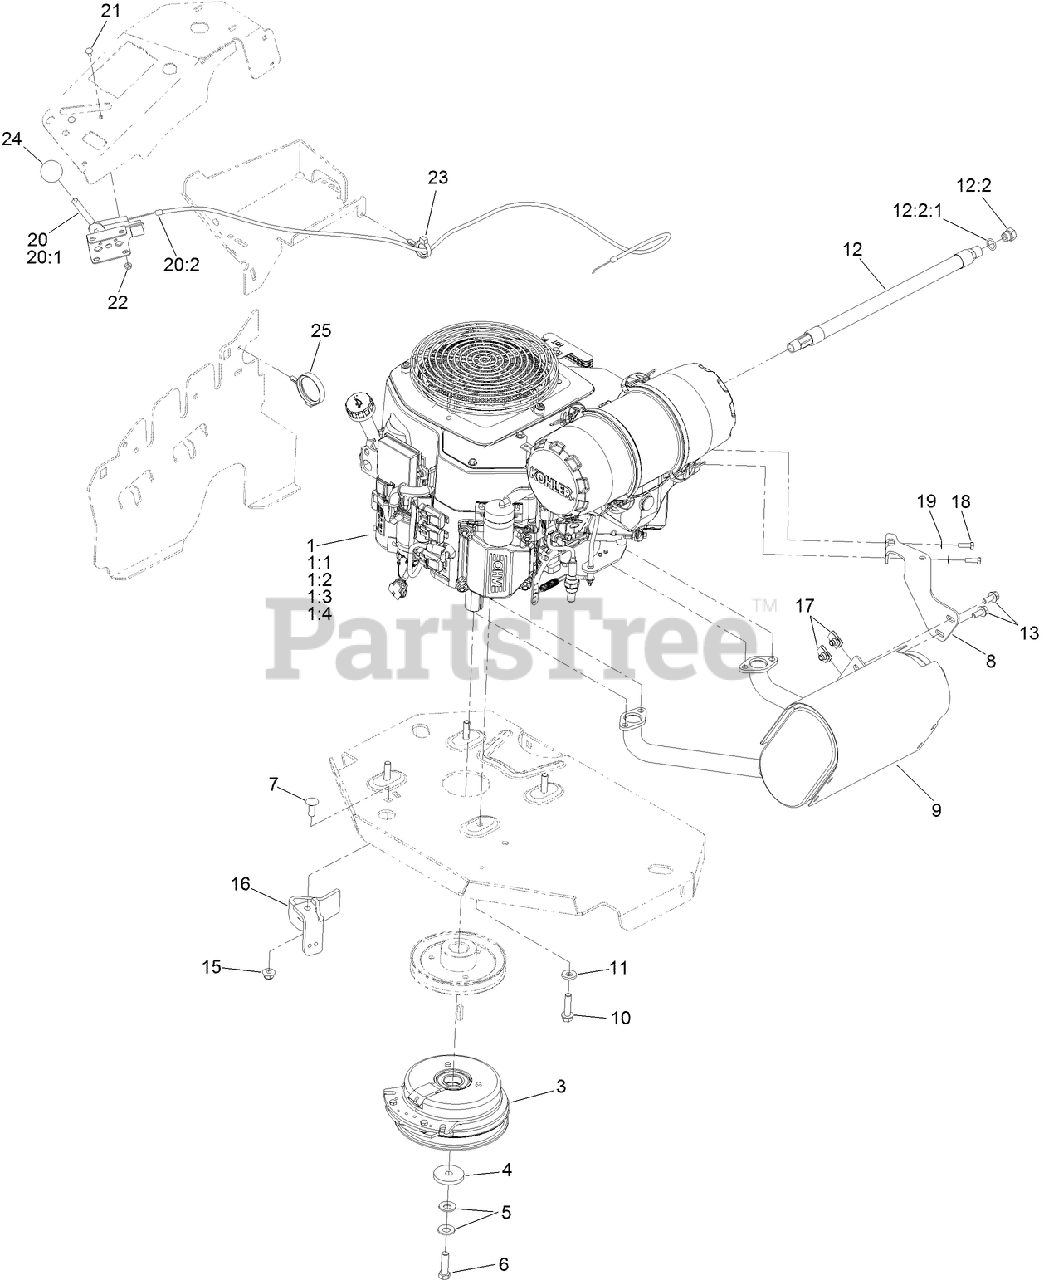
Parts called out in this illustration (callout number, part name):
1:1	KOHLER 52 050 02-S ENGINE OIL FILTER
1:2	KOHLER 25 083 01-S ENGINE AIR FILTER
1:3	KOHLER 25 083 04-S SAFETY FILTER
1:4	KOHLER 25 050 50-S Propane Fuel Filter
3	CLUTCH KIT
4	WASHER-CLUTCH
5	WASHER-SPRING
6	SCREW-HH
7	SCREW-CARR
8	MUFFLER BRACKET KIT
9	MUFFLER KIT
10	SCREW-HWH
11	WASHER-BELLEVILLE
12	OIL DRAIN HOSE ASM
12:2	PLUG-HH
12:2:1	O-RING
13	SCREW-HHF
15	NUT-HF, NI
16	CLUTCH-ANCHOR
17	NUT-U
18	SCREW-HH
19	WASHER-SPRING
20	THROTTLE CONTROL ASM
20:1	LEVER-THROTTLE
20:2	CABLE-THROTTLE
21	BOLT-CARR
22	NUT-LOCK, NI
23	CLAMP-HOSE
24	KNOB-BALL
25	CLAMP-HARNESS
